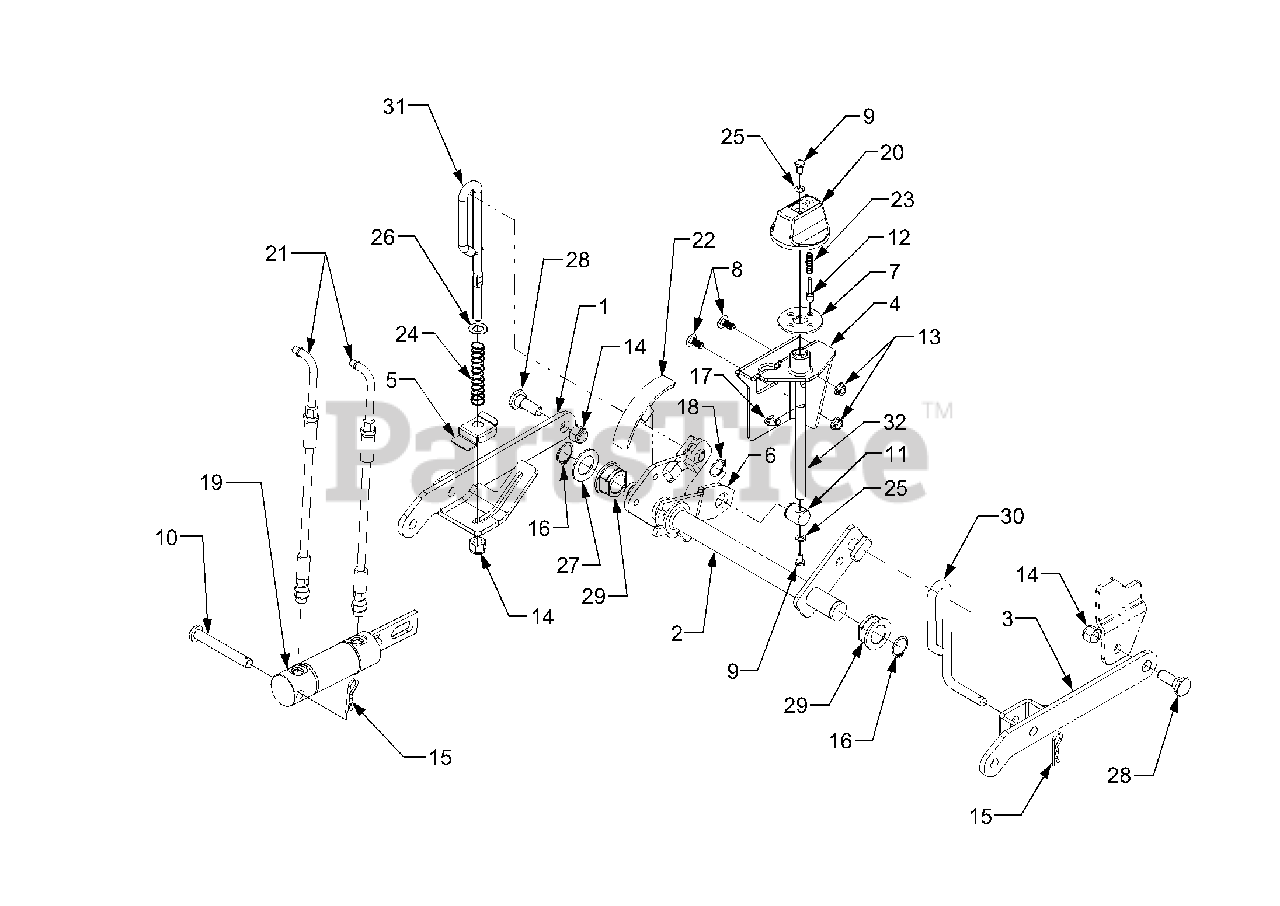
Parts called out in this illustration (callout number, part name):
1	Link, LH Lift
4	Bracket, Downstop
5	Stop Bracket, Lift Rod
6	Arm, Downstop
7	Disk, Detent
8	Bolt, Carriage, 3/8-16 x .75
9	Screw, Hex Cap, 1/4-20 x .5 GR5
10	Pin, Clevis, .5 x 3.75
11	Ferrule, Adjustment
12	Pin, Detent Plunger
13	Nut, Flange Lock, 3/8-16 GR5
14	Nut, Hex Lock, 1/2-13
15	Pin, Internal Cotter
16	Snap Ring, 1.0 Dia. Shaft
17	Ring, 'E' Retaining, .5 Dia
18	Snap Ring, .875 Dia. Shaft
19	Cylinder, Center Lift
20	Knob
21	Hose, Lift
22	Indicator, Lift Position
23	Spring, Compression
24	Spring, Compression
25	Washer, Flat, .281 x .5 x .063
26	Washer, Flat, .536 x .93 x .050
27	Washer. Flat, 1.0 x 1.7 x .10
28	Shoulder Screw
29	Bearing, Flange w/Flats
30	Rod, RH Lift
31	Rod, LH Lift
32	Screw, Adjustment
